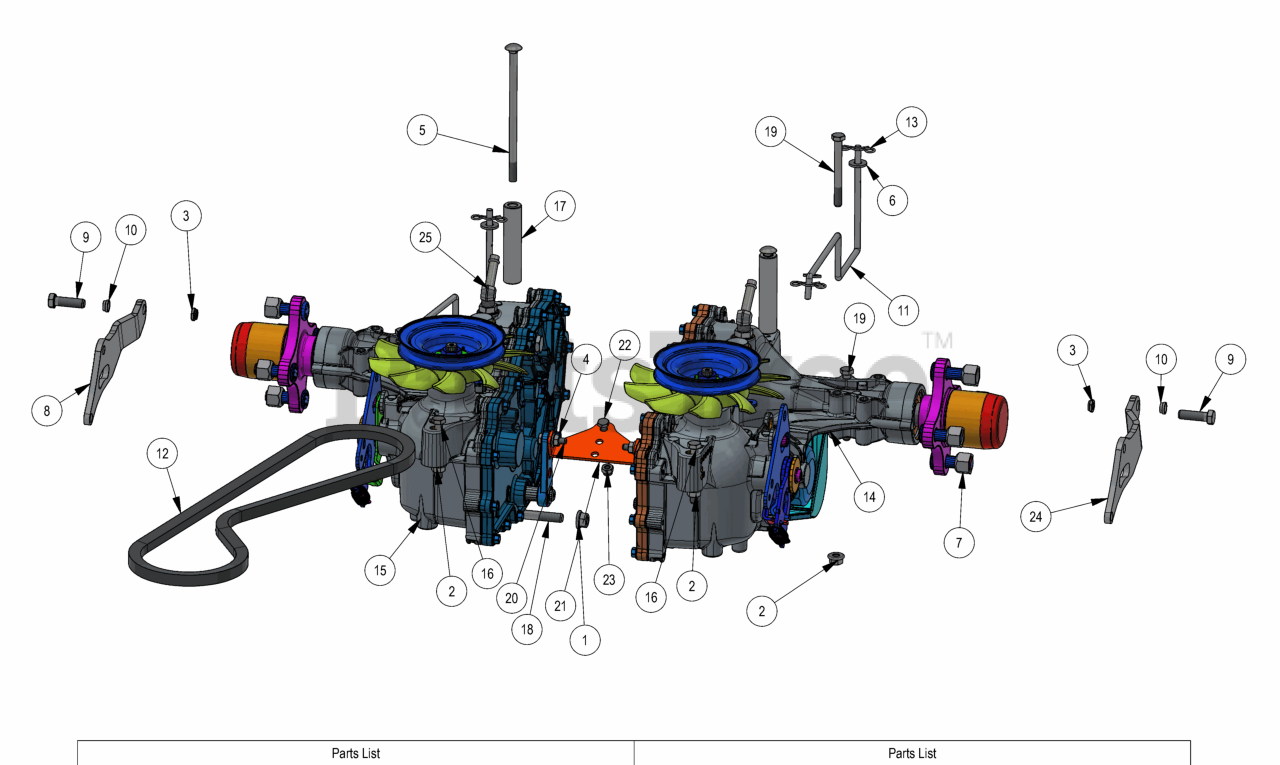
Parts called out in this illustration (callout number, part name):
1	3/8 Nylock Flange Nut
2	5/16-18 NYLON INSERT FLANGE LOCKNUT ZINC
3	5/16-18 Nylock Jom Nut
4	1/4-20 NYL INSERT FLANGE LOCKNUT ZINC
5	5/16-18 X 6 CARRIAGE BOLT (GR.5) ZINC
6	1/4 USS FLAT WASHER (3/4 OD) ZINC
7	Acorn Lug Nut
8	SD Control Arm Plate RH
9	3/8-16 X 1-1/4 HEX CAP SCREW (GR.5) ZINC
10	Drive Arm Transaxle Spacer
11	2019 Stand On Neutral Rod
12	2020 Renegade Pump Belt, 42.99"
14	ZK-MMBC-SBKC-1PXX
15	ZK-JMBC-SBKB-1PXX
16	5/16-18 X 2-1/2 HEX CAP SCREW (GR.5) ZINC
17	2017 Transaxle Spacer
18	3/8-16 X 2 HEX CAP SCREW (GR.5) ZINC
19	5/16-18 X 3 HEX CAP SCREW (GR.5) ZINC
20	1/4-20 X 1 HEX CAP SCREW (GR.5) ZINC
21	2020 36" Brake Bracket 2020 36" Stand On
22	1/4-20 X 3/4 HEX CAP SCREW (GR.5) ZINC
23	1/4-20 NYLON INSERT LOCKNUT ZINC
24	SD Control Arm Plate LH
25	ZT Fitting, 3/8 x 3/8 45 Degree, 4603-6-6
